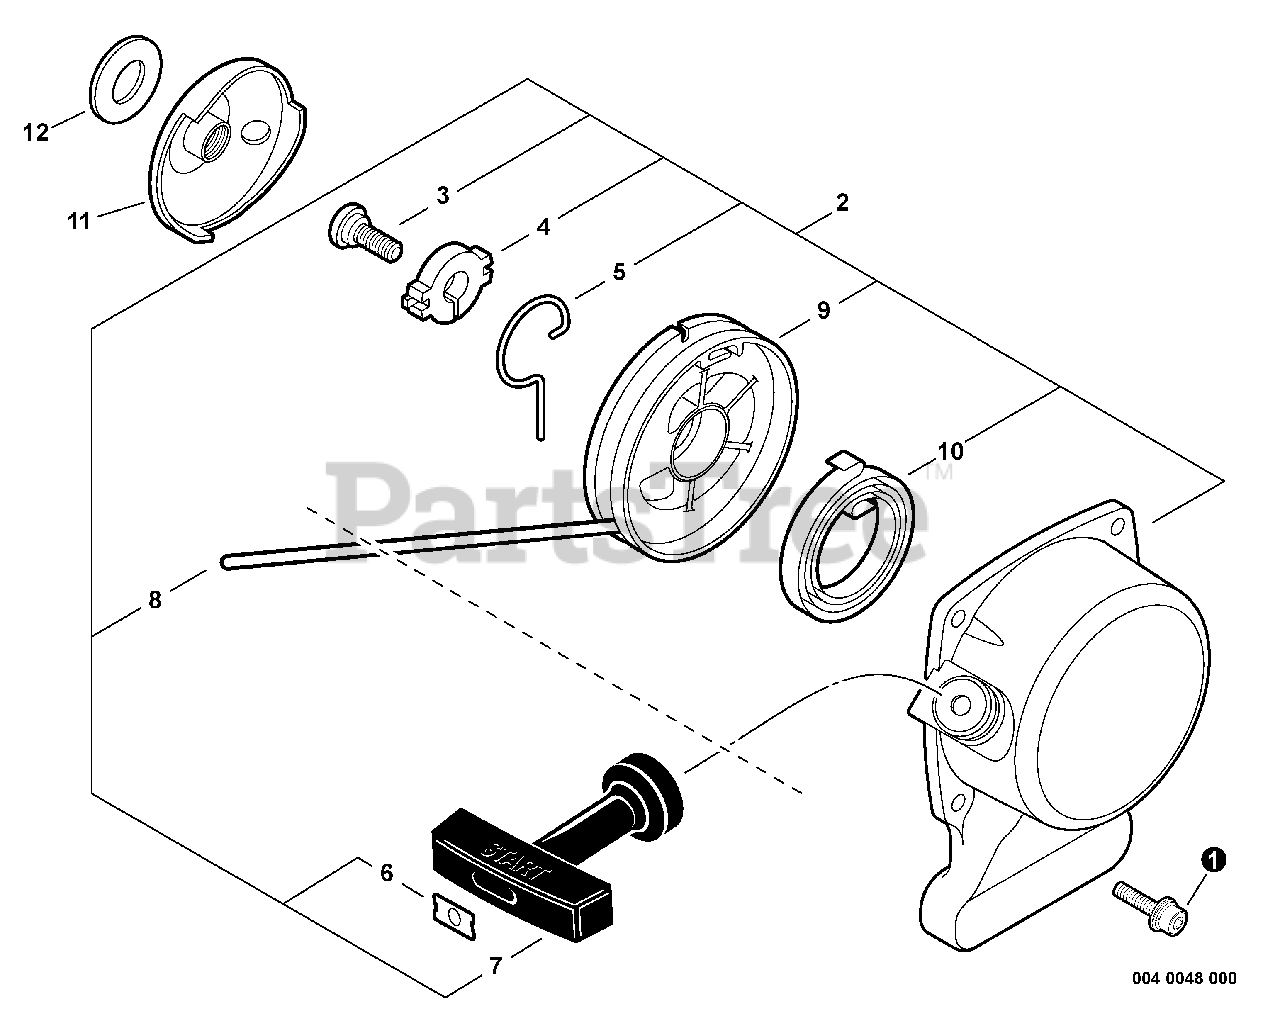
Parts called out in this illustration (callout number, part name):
1	SCREW - 4X16
2	STARTER ASSY
3	SCREW - 5
4	RETAINER, PAWL
5	PAWL, STARTER
6	RETAINER, ROPE
7	GRIP, STARTER
8	ROPE, STARTER
9	REEL, ROPE
10	SPRING, REWIND
11	PAWL, STARTER
12	WASHER - 8
